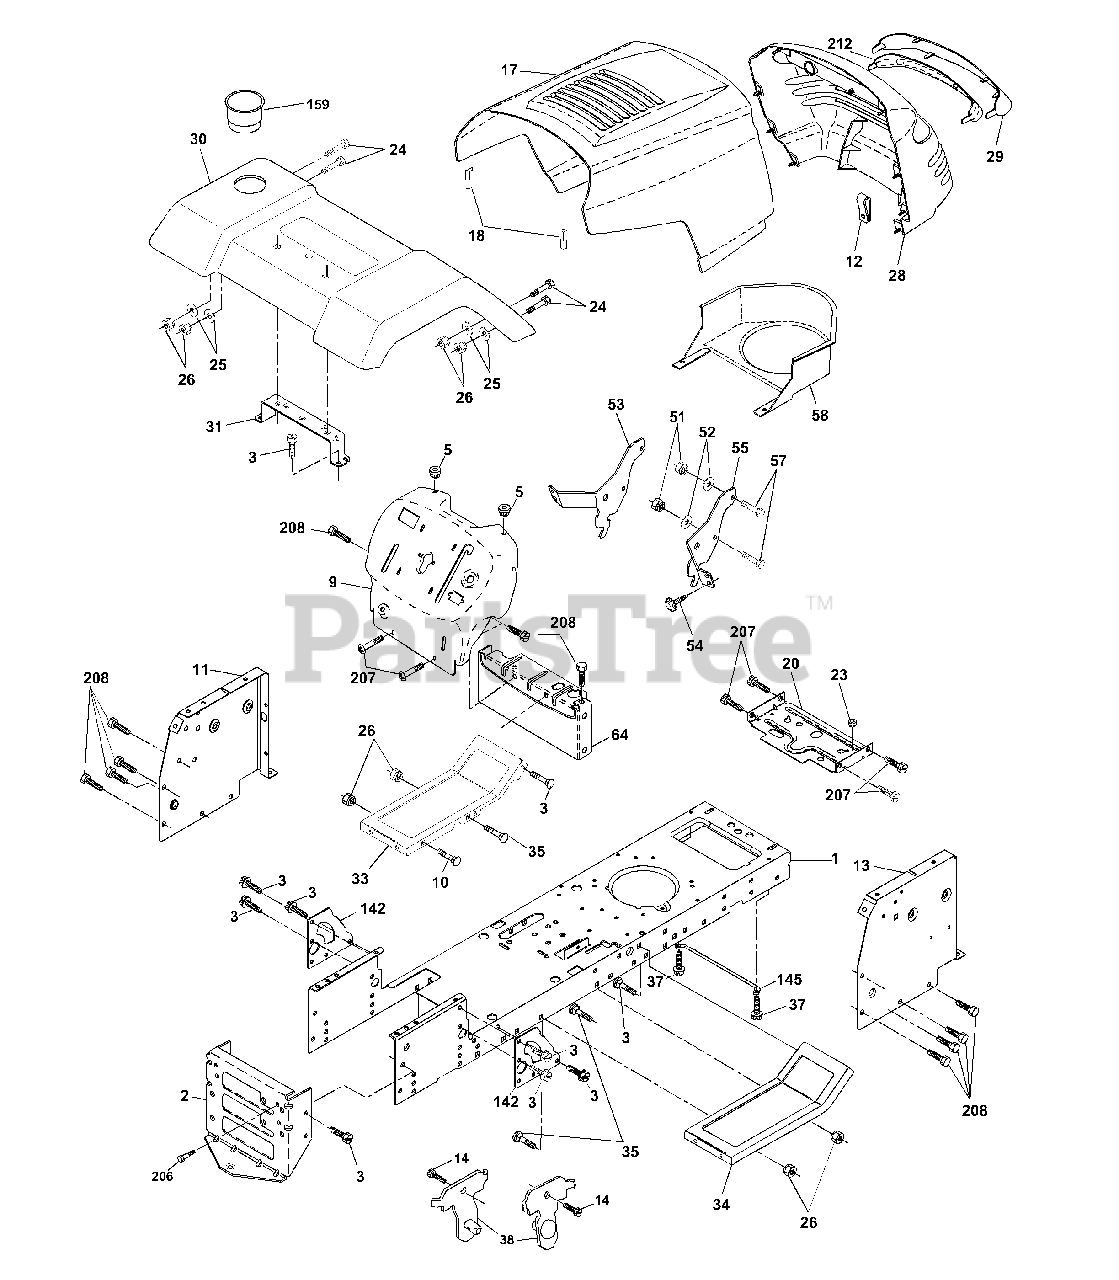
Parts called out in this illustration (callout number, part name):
1	Chassis stamping
2	Drawbar, 12 Ga.
3	Screw 3/8-16x3/4
5	Bumper Hood/Dash
9	Dash Slkscr
10	Bolt Carriage 3/8-16 x 1
11	Panel Dash Lh
12	Clip Tinnerman
13	Panel Dash Rh
17	Hood P/L LT
18	Bumper Hood
20	Plate Mtg Battery Fuel Tank Fr
24	Bolt Fin Hex 3/8-16 x 1 Gr. 5
25	Washer 13/32 X 13/16 X 12 Ga
26	Nut Lock Hex w/Ins. 3/8-16 Unc
28	Grille/Lens Asm
29	Lens
30	Fender
31	Bracket Fender
33	Footrest Pnt Lh
34	Footrest Pnt Rh
35	Bolt Rdhd Sht Sqnk 3/8-16 x 3/4
37	Screw Thdrol 6/16-18 x 1/2 TYT
38	Bracket Asm Pivot Mower Rear
51	Nut Lock w/Insert 1/4-20 Unc
52	Washer 9/32 x 7/8 x 16 Ga.
53	Bracket Grille Lh
54	Screw Hex Wsh 8-18 x 7/8
55	Bracket Grille Rh
57	Bolt Hex 1/4-20 x 3/4
58	Air Duct Engine P/L
64	Dash Lower STLT
142	Plate Reinforcement STLT
145	Rod Pivot Chassis/Hood
159	Cupholder Stlt Grey
205	Screw Thdrol. 3/8-16 x 1/2
206	Bolt Shoulder 5/16-18 TT
207	Screw Thdrol 5/16-18 x 1/2
208	Screw Thdrol 3/8-16 x 1/2
212	Insert Lens Reflective
